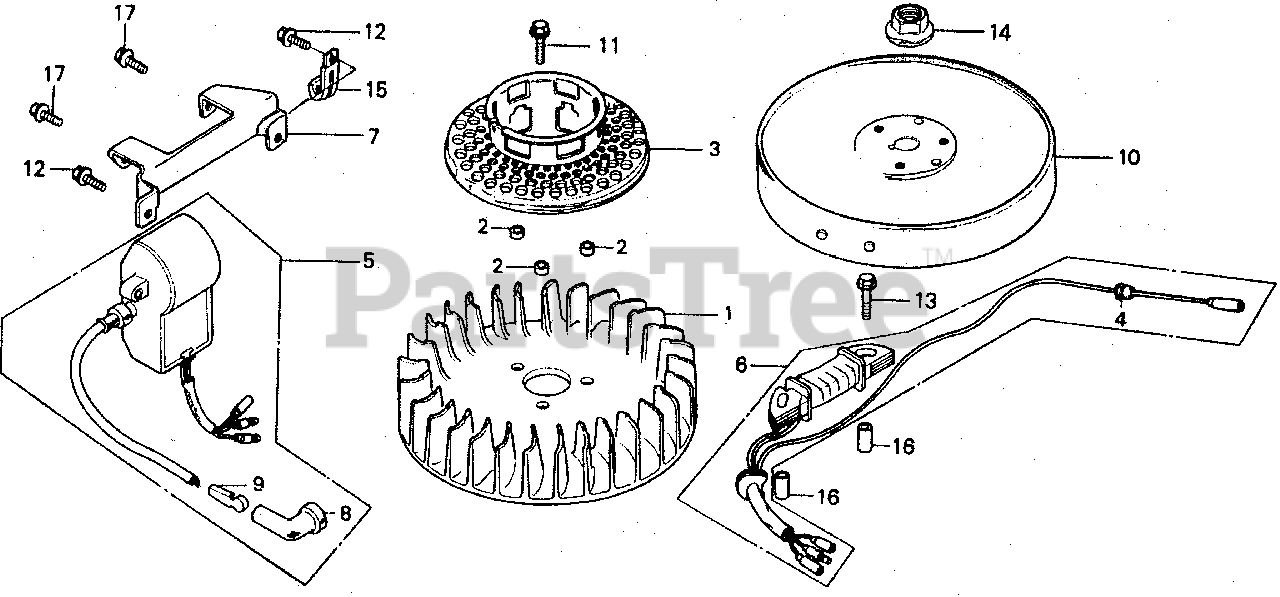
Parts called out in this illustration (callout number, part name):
1	FAN, COOLING
2	COLLAR, FAN
3	PULLEY, STARTER
4	GROMMET, PRIMARY WIRE (NOT AVAILABLE)
5	MODULE, IGNITION CONTROL (CDI)
5	MODULE, IGNITION CONTROL (CDI) (NOT AVAILABLE)
6	COIL ASSY., EXCITER (NOT AVAILABLE)
7	STAY, IGNITION CONTROL MODULE (CDI) (NOT AVAILABLE)
8	CAP, IGNITION
8	CAP, IGNITION (TOYO)
9	TERMINAL, PLUG
10	FLYWHEEL (C.D.I.) (NOT AVAILABLE)
11	BOLT, FLANGE (6X16)
12	BOLT, FLANGE (6X12) (CT200)
13	BOLT, FLANGE (6X28) (CT200)
14	NUT, SPECIAL (14MM)
15	CLIP, WIRE
16	PIN, DOWEL (8X14)
17	BOLT, FLANGE (6X12)
